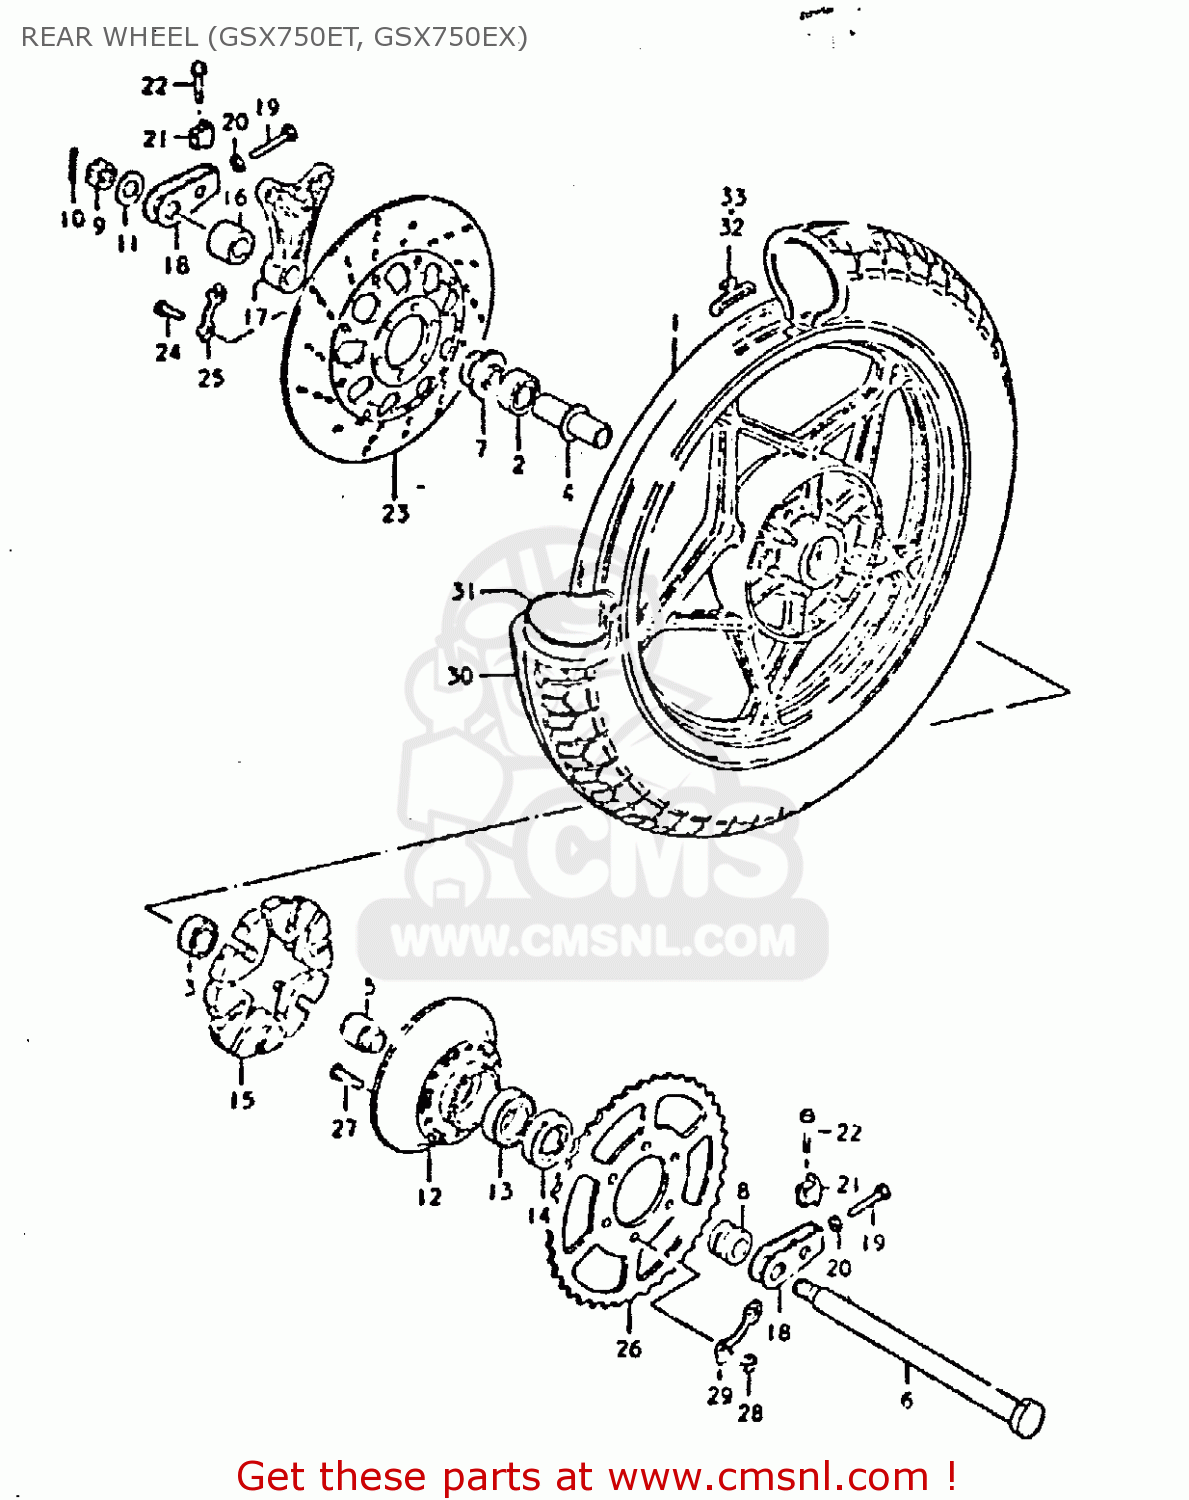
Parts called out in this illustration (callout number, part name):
1	WHEEL, REAR
2	BEARING WHEEL REAR(20X47X14)
3	BEARING, LH
4	SPACER,REAR HUB BEARING
5	SPACER,REAR HUB BEARING
6	AXLE,REAR
7	SPACER,REAR AXLE
8	SPACER(20X33X28.3)
9	NUT 18MM
10	PIN,COTTER
11	WASHER(19X34X4)
12	DRUM,REAR SPROCKET MOUNT
13	BEARING
14	SEAL,OIL(33X62X7)
15	ABSORBER,REAR HUB SHOCK
16	SPACER (20X38X17)
17	BRACKET,RR,CALIPER
18	ADJUSTER,CHAIN
19	BOLT
20	NUT
21	SUPPORTER,CHAIN ADJUST
22	BOLT (8X40)
23	DISC,RR BRAKE
24	BOLT(8X30)
25	WASHER
26	SPROCKET,RR
27	BOLT
28	NUT
29	WASHER
30	TIRE
31	TUBE,INNER
32	BALANCER,WHEEL
33	BALANCER,WHEEL
